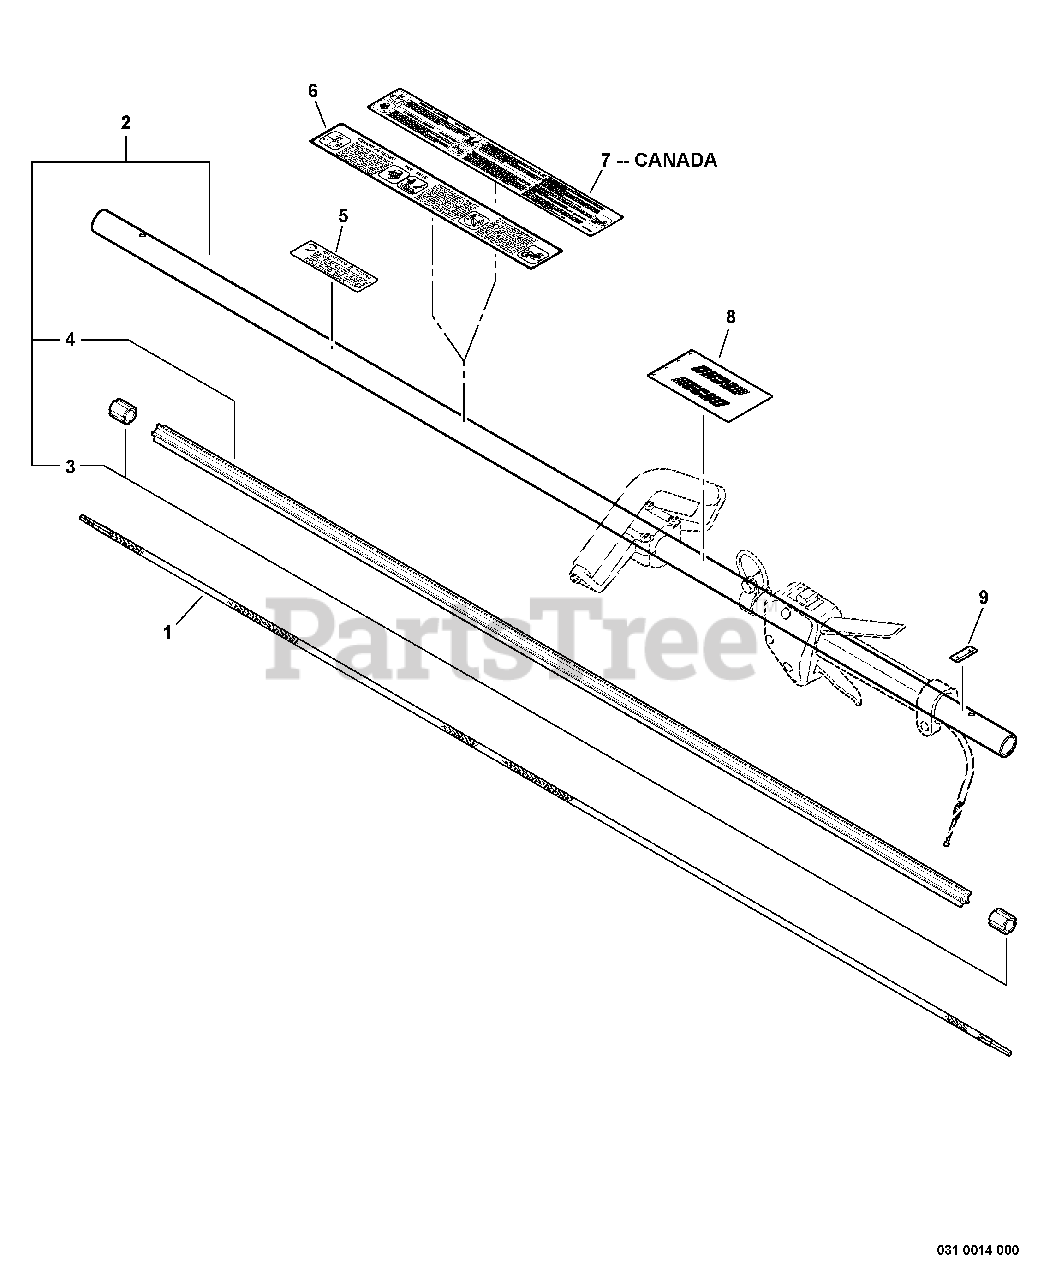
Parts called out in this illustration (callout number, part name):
1	DRIVESHAFT - FLEXIBLE
2	MAIN PIPE ASSY
4	LINER - FLEXIBLE
5	LABEL - CAUTION -- SPANISH
6	LABEL - CAUTION
7	LABEL - CAUTION
8	LABEL - HANDLE LOCATION
9	LABEL - ALIGNMENT
